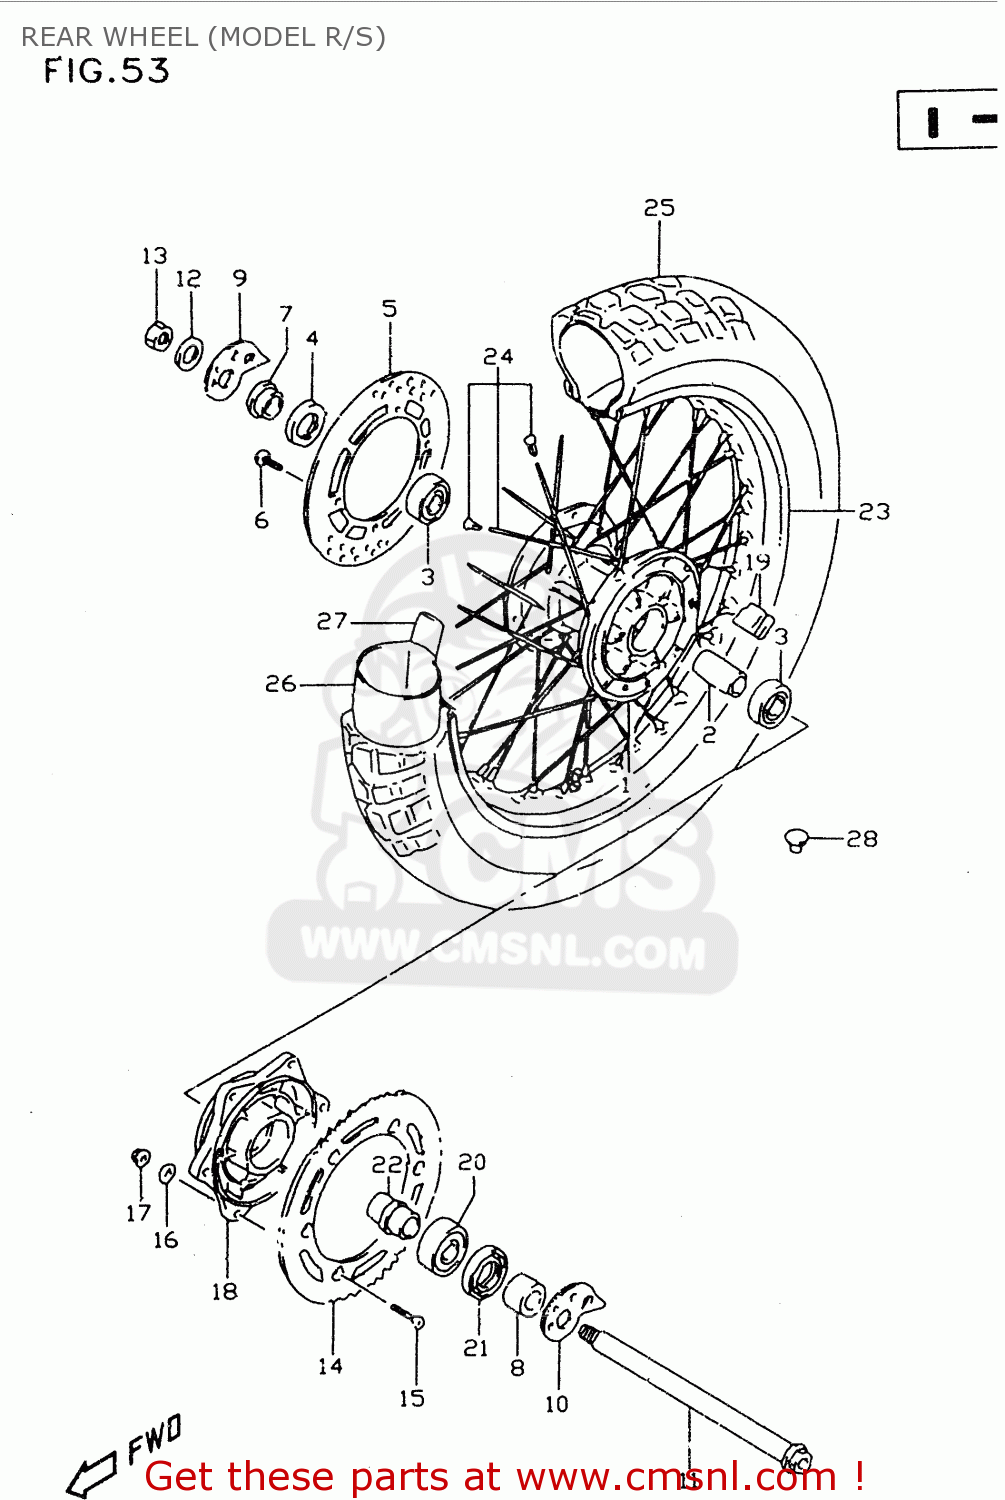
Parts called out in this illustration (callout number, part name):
1	HUB,RR WHEEL
2	SPACER,RR HUB BEARING
3	BEARING
4	SEAL,OIL(26X47X5)
5	DISC,RR BRAKE
6	BOLT
7	SPACER,RR AXLE,R
8	SPACER,RR AXLE,L
9	ADJUSTER,CHAIN,R
10	ADJUSTER,CHAIN,L
11	AXLE,RR
12	WASHER(19X32X3.2)
13	NUT 18MM
14	SPROCKET,RR(NT:41)
15	BOLT(8X30.5)
16	WASHER
17	NUT
18	DRUM,REAR SPROCKET MOUNT
19	ABSORBER,RR HUB SHOCK
20	BEARING(25X52X15)
21	SEAL,OIL(34X52X6)
22	RETAINER,RR SPROCKET DRUM
23	RIM,REAR WHEEL (18X2.15)
24	SPOKE SET,RR WHEEL
25	TIRE,REAR 4.60-18
26	TUBE ASSY,INNER
27	PROTECTOR, INNER TUBE
28	CAP(OD:12)
